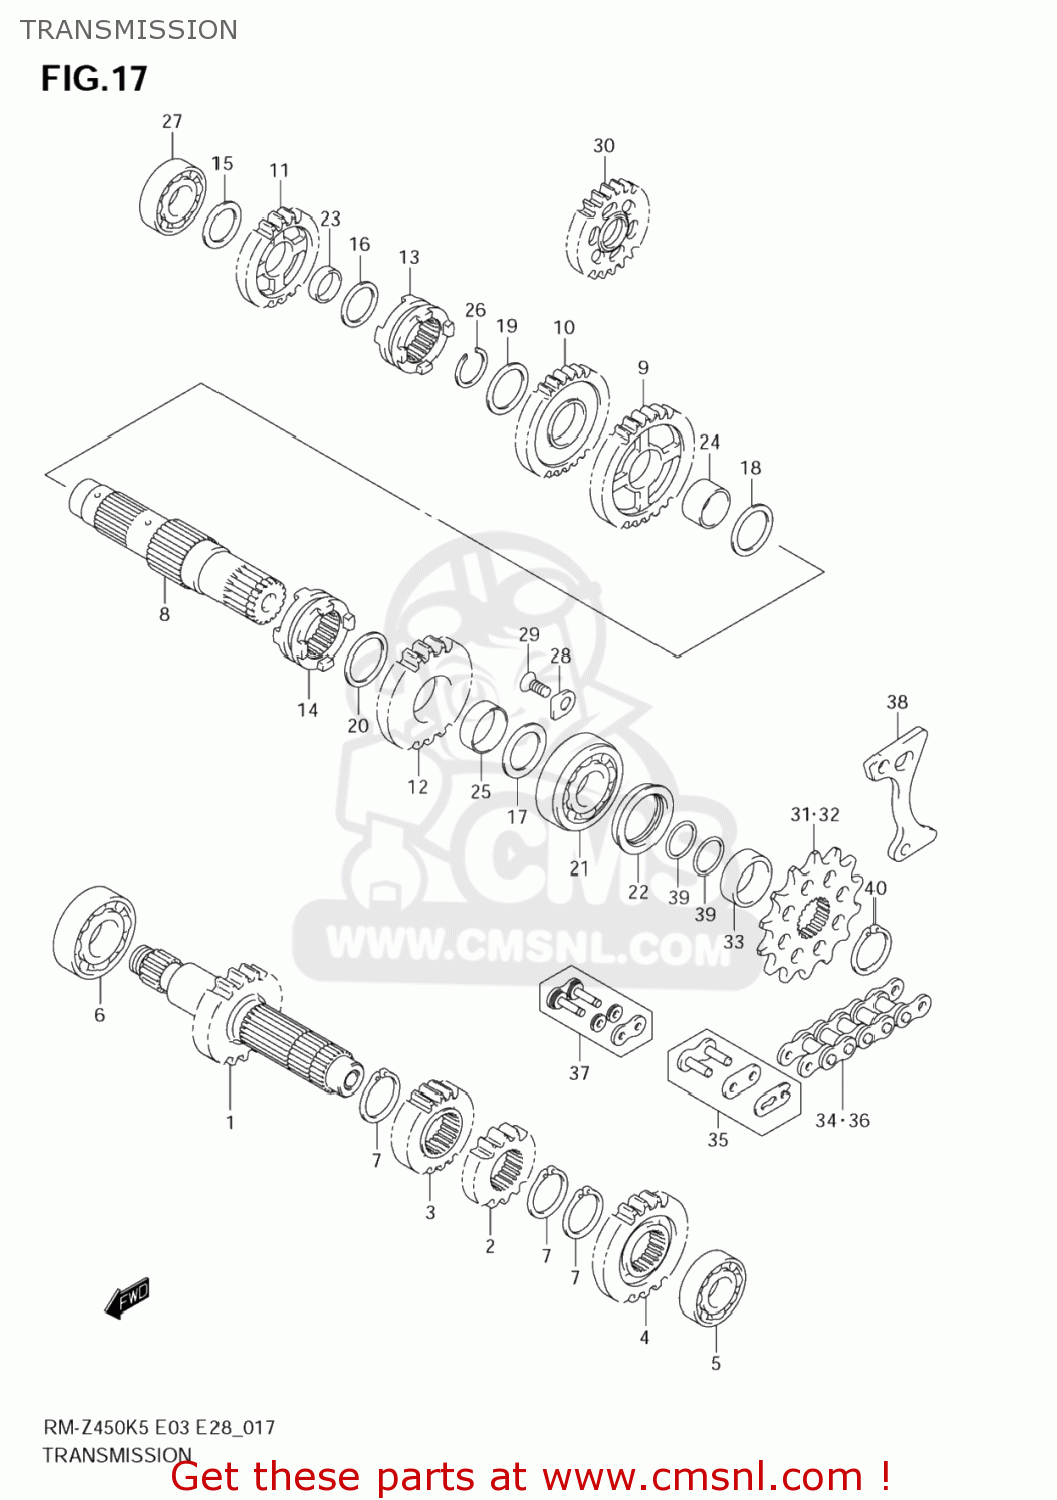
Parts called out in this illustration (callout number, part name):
1	SHAFT,COUNTER
2	GEAR,1ST DRIVE(NT:15)
3	GEAR,2ND DRIVE(NT:18)
4	GEAR,4TH DRIVE(NT:22)
5	BEARING
6	BEARING
7	CIRCLIP
8	SHAFT,DRIVE
9	GEAR,1ST DRIVEN(NT:30)
10	GEAR,2ND DRIVEN(NT:29)
11	GEAR,3RD DRIVEN(NT:27)
12	GEAR,4TH DRIVEN(NT:25)
13	DOG,SLIDING NO.1
14	DOG,SLIDING NO.2
15	SHIM(20X28X1)
16	SHIM(22X28X0.5)
17	SHIM(24X34X1)
18	SHIM(25X32X1)
19	SHIM(25X32X1)
20	SHIM(27X33X1)
21	BEARING(24X56X14)
22	SEAL,OIL(31X40X8.5)
23	BUSH(22X25X9)
24	BUSH(25X28X17)
25	BUSH(27X30X9)
26	CIRCLIP
27	BEARING
28	RETAINER,COUNTER BEARING,R
29	SCREW(6X12)
30	GEAR,KICK STARTER IDLE
31	SPROCKET,ENGINE(14T)
32	SPROCKET,ENGINE(NT:13)
33	SPACER,ENGINE
34	CHAIN ASSY,DRI
35	JOINT SET,CHAIN
36	CHAIN ASSY(DID
37	JOINT SET,CHAI
38	PLATE,FRONT CH
39	O RING(D:1.9,ID:21.8)
40	CIRCLIP
